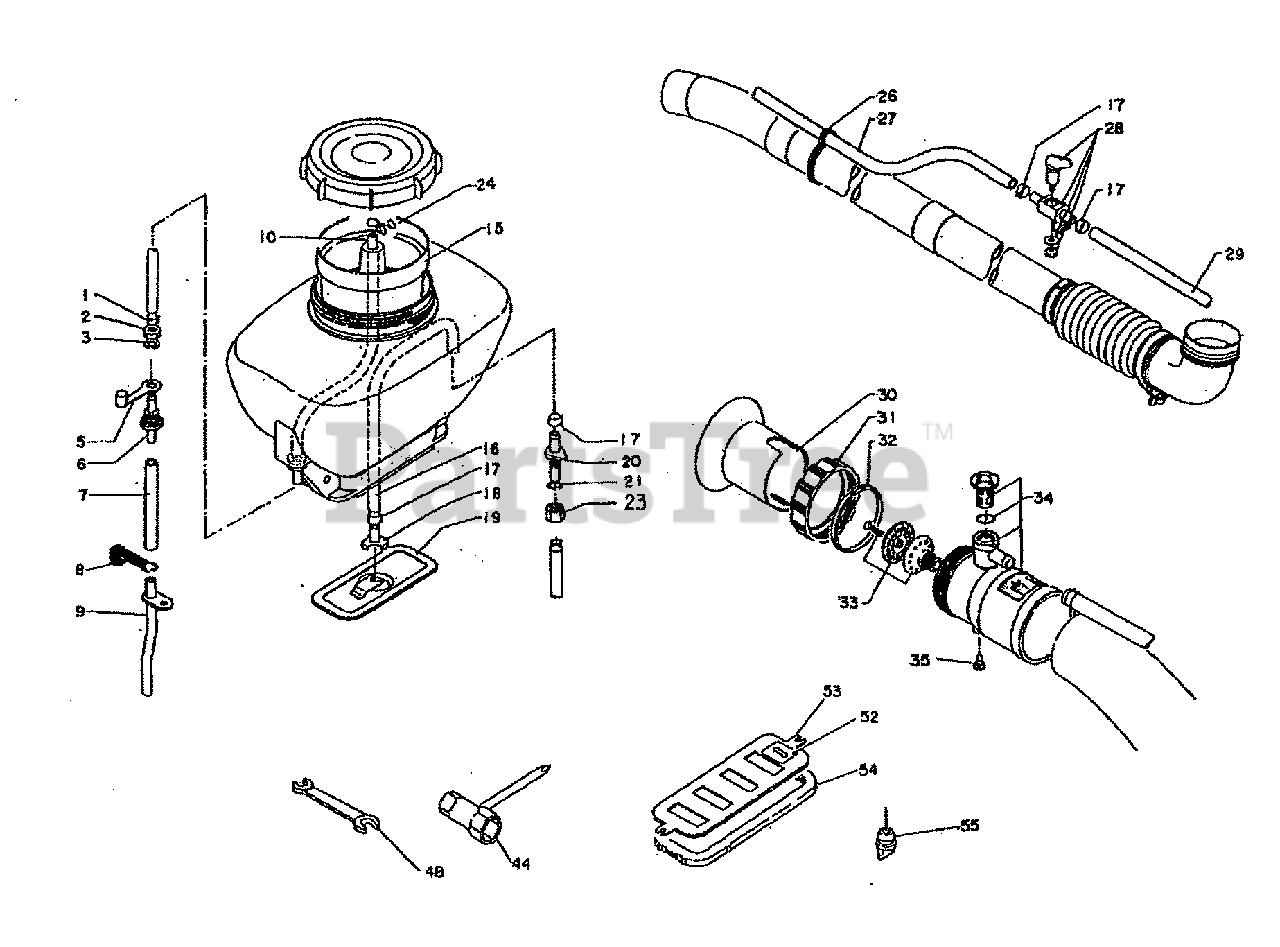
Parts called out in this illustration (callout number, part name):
1	CLAMP
3	WASHER 12×20×1
6	CONNECTOR, PIPE
7	PIPE, OUTER PRESSURE 7×11×170L
9	TUBE
10	PIPE, INNER PRESSURE 7×11×500BL
15	FILTER, TANK
16	TUBE
17	CLAMP
18	CONNECTOR
19	PLATE
20	CONNECTOR, PIPE
21	O-RING 3×13
24	CLIP
26	CLIP
27	TUBE, VINYL
28	VALVE
34	HOLDER, NOZZLE
44	LABEL, CAUTION
48	SPANNER 10×13
53	SHUTTER ASSY
56	PLUG, RUBBER
